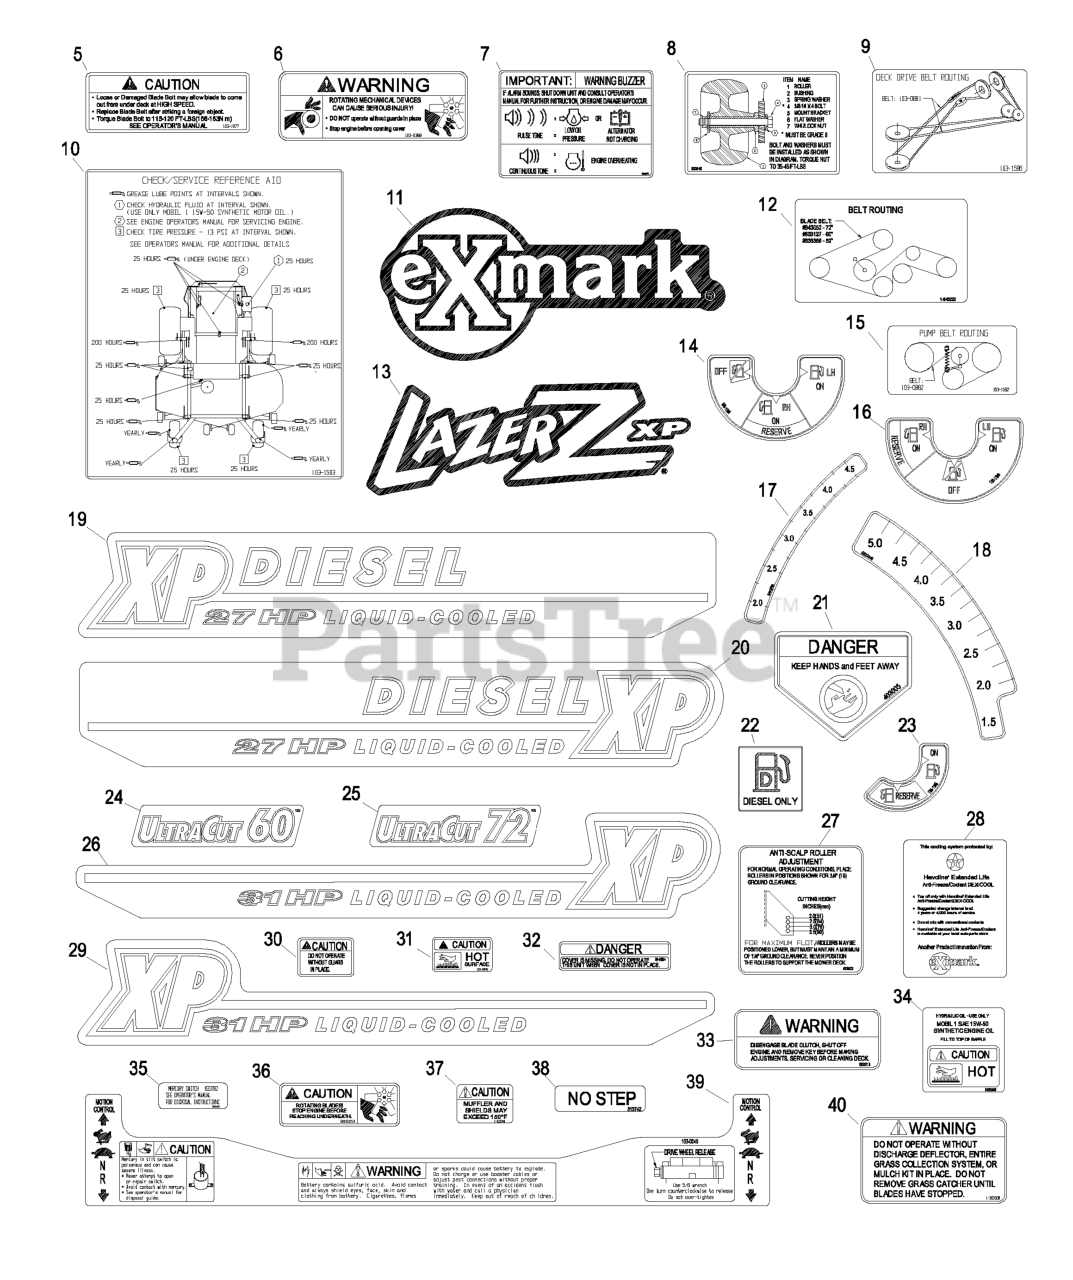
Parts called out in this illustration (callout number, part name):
5	DECAL,BOLT TORQUE
7	DECAL-BUZZER, WARNING
8	DECAL,ROLLER MOUNTING
9	DECAL,BELT ROUTING XP
10	DECAL,CHECK/SERVICE XP *
11	DECAL, EXMARK LOGO
12	DECAL,BELT ROUTING
16	DECAL, FUEL VALVE XPG
17	DECAL-HEIGHT, DECK
18	DECAL-HEIGHT, DECK
21	DECAL-DANGER
22	DECAL-FUEL
24	DECAL,ULTRACUT 60
25	DECAL,ULTRACUT 72
27	DECAL,ANTISCALP
28	DECAL,SHELL COOLANT
30	DECAL-GUARD
31	DECAL-CAUTION
32	DECAL-COVER, MISSING
33	DECAL,WARNING
35	DECAL-SWITCH, MERCURY
36	DECAL-FAN, RADIATOR
38	DECAL,NO STEP
39	DECAL-CONSOLE, TOP
40	DECAL-WARNING, DISCHARGE
